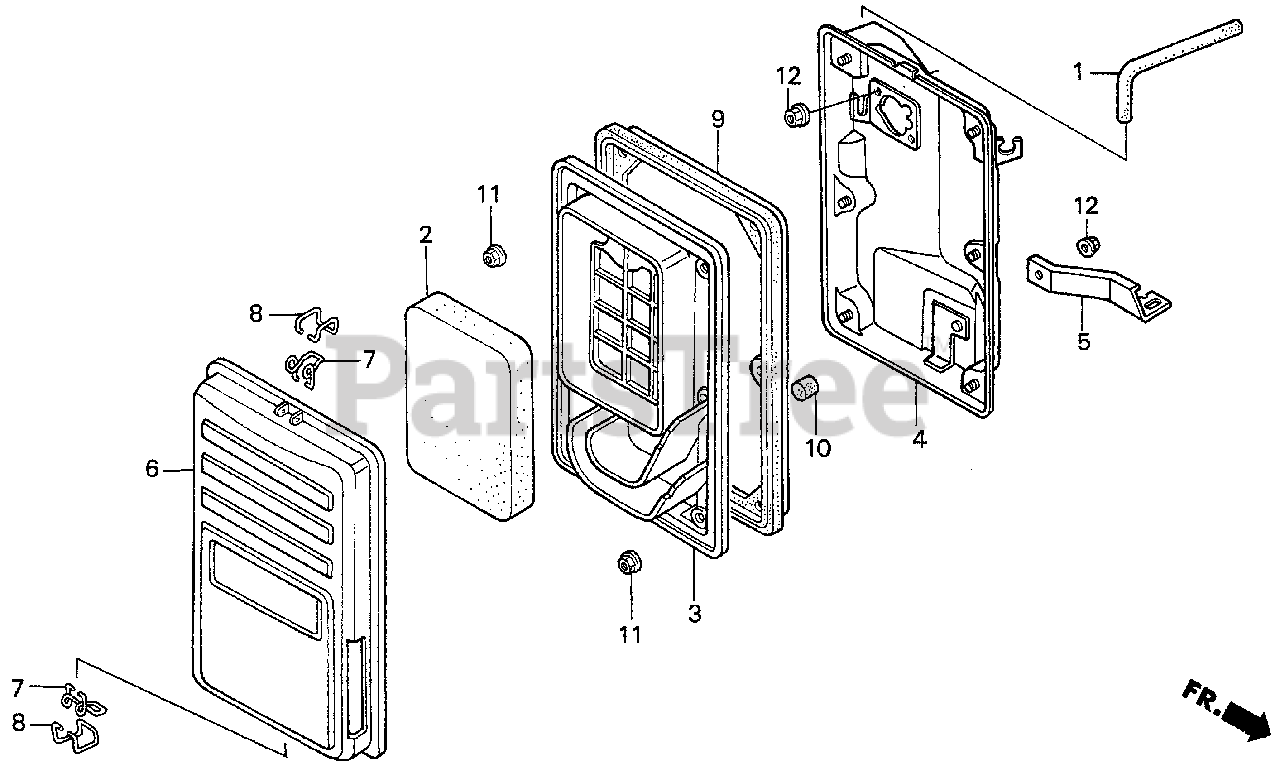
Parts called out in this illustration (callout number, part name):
1	TUBE, BREATHER
2	ELEMENT, AIR CLEANER
3	SEPARATOR, AIR CLEANER
4	HOUSING, AIR CLEANER
5	STAY, AIR CLEANER
6	COVER, AIR CLEANER
7	CLIP A, AIR CLEANER WIRE
8	CLIP B, AIR CLEANER WIRE
9	SEAL, AIR CLEANER
10	FILTER, DRAIN TUBE
11	NUT, FLANGE (5MM)
12	NUT, FLANGE (6MM)
